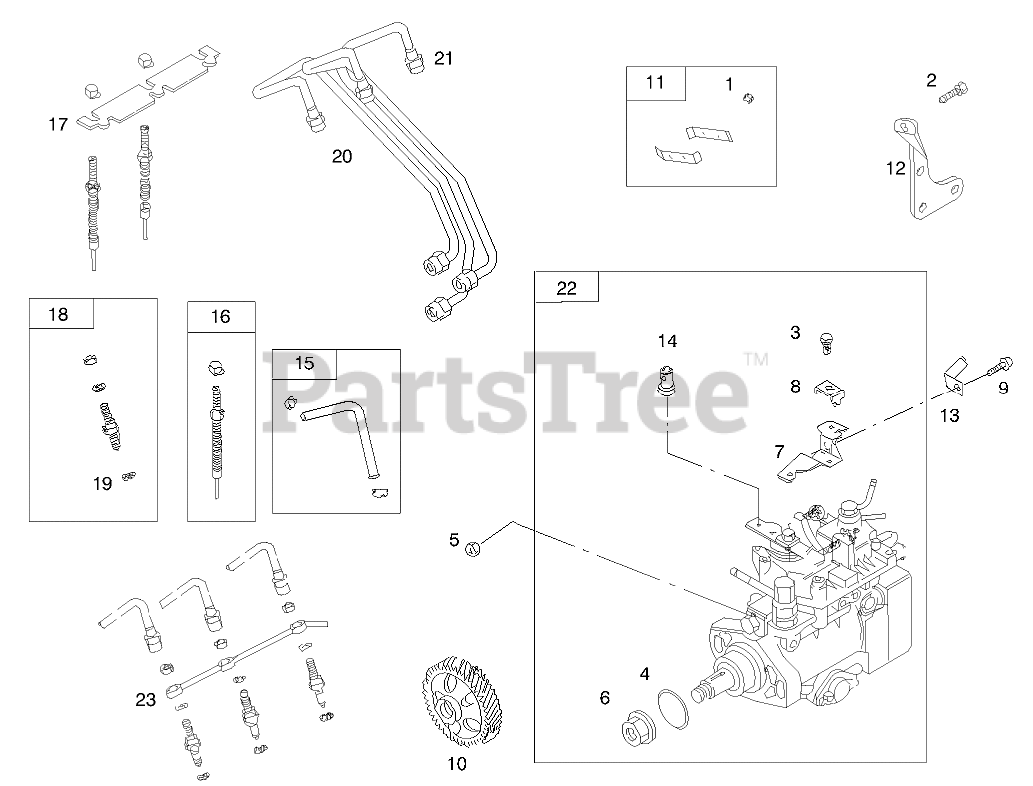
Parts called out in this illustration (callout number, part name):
1	SCREW-HEX
2	SCREW-HEX
3	Screw-Metric
4	O-RING
5	NUT-HEX, METRIC
6	NUT-HEX, METRIC
7	BRACKET-CLAMP, CASING
8	Clamp-Casing
8	SWITCH-TEMPERATURE, WATER
9	SCREW-HEX
9	GASKET-SET
10	GEAR-DRIVE
11	CLAMP
12	BRACKET-SUPPORT
13	Bracket-Support
14	CLAMP-SWIVEL
14	VALVE OVERHAUL KIT
15	HOSE / CLAMP ASM
15	SHAFT-GEAR
16	PLUG-GLOW
17	STRAP-PLUG, GLOW
18	NOZZLE-INJECTOR
19	SEAT-INJECTOR
20	PIPE-INJECTOR, NO. 2
21	PIPE-INJECTOR, NO. 3
22	PUMP-INJECTION
23	PIPE-RETURN, FUEL
